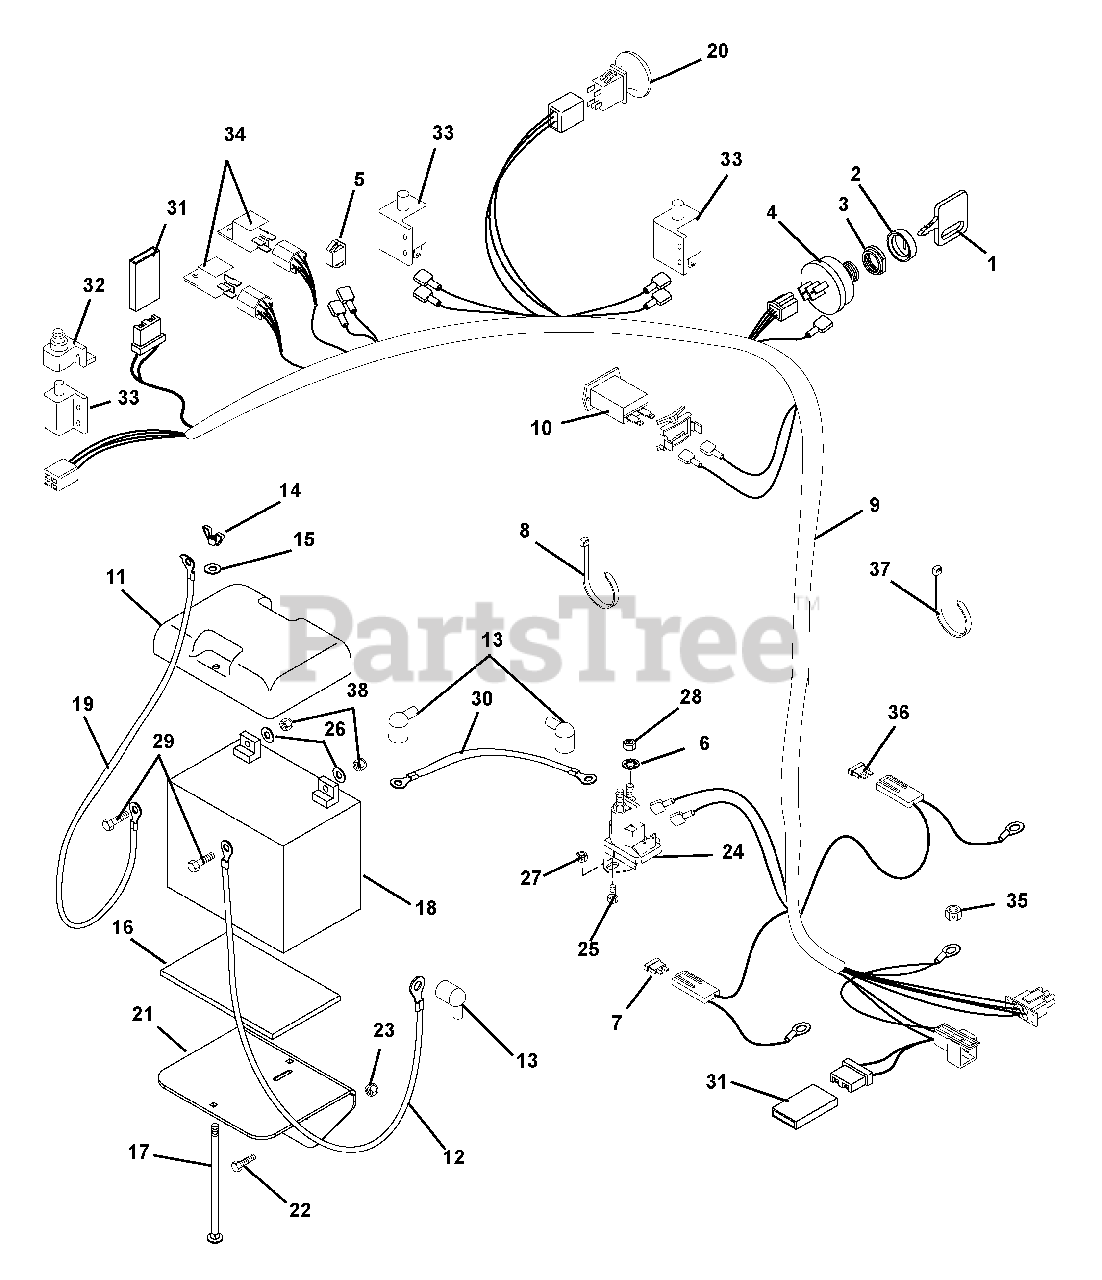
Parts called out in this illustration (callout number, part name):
1	KEY -W/CAP
2	CAP - IGNITION SWITCH
3	NUT- PANEL .562-24 GRECO
4	KEY SWITCH
5	LIGHT,INDICATOR
6	WSHR-LOCK INT .31 YWZC
7	FUSE-25 AMP ATC TYPE
8	CABLE TIE LG 5-1/2
9	WIRE HARNESS-ERGO HYDRO ELEC.
10	HOURMETER-QUARTZ 80VDCMAX
11	COVER, BATTERY
12	START CABLE 22"
13	BOOT, EYELET TERMINAL
14	NUT-LK WING .250-20 YWZC
15	@WSHR-FL-STL.281X.62X.065 YWZC
16	PAD,BATTERY
17	@BLT-RDHDSQNK .25-20X7.00 G2YZ
18	BATTERY, 300 CCA 10U1L
19	CABLE, NEGATIVE BATTERY 24.00
20	SWITCH - PTO - NMIR
21	WELDMENT, BATTERY TRAY
22	@BLT-HEX .38-16X1.00 GR5 YWZC
23	@NUT-LK-NYL .38-16 YWZC
24	SOLENOID
25	@BLT-HEX .25-20X.75 GR5 YWZC
26	@WSHR-FL-STL.281X.62X.065 YWZC
27	@NUT-SPNLK-FLG .25-20 YWZC
28	NUT-JAM .31-24 YWZC
29	@BLT-HEX .25-20X.75 GR5 YWZC
30	STARTER CABLE 6.75"
31	DIODE, CONNECTOR SHELL
32	BOOT, RUBBER
33	SWITCH,INTERLOCK
34	RELAY
35	@NUT-LK-TOP-FLG .31-18 YWZC
36	FUSE 20AMP
37	TIE WRAP
38	@NUT-LK-NYL .250-20 YWZC
